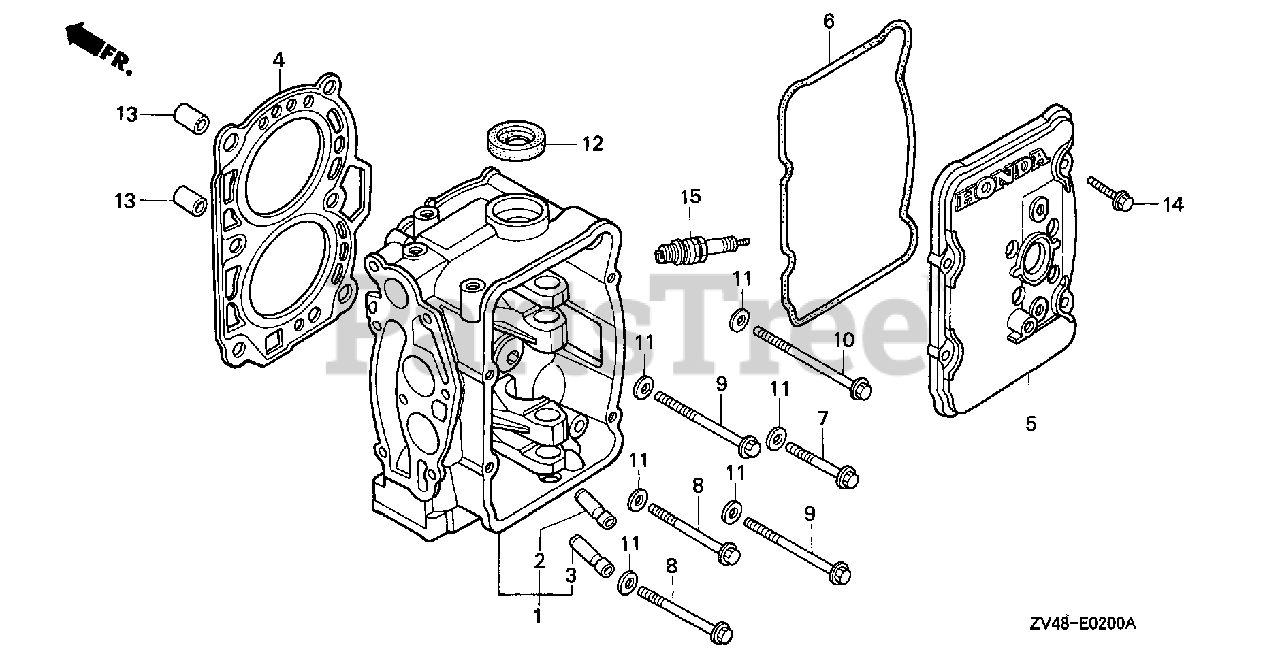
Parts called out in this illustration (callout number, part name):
1	CYLINDER HEAD *NH8* (DARK GRAY)
2	GUIDE, VALVE (OVER SIZE)
3	GUIDE, EX. VALVE (OVER SIZE)
4	GASKET, CYLINDER HEAD
5	COVER, CYLINDER HEAD *NH8* (DARK GRAY)
6	GASKET, HEAD COVER
7	BOLT, FLANGE (8X57)
8	BOLT, FLANGE (8X72)
9	BOLT, FLANGE (8X77)
10	BOLT, FLANGE (8X87)
11	WASHER, HEAD (8MM)
12	OIL SEAL (18X30X7) (NOK)
13	PIN, DOWEL (10X16)
14	BOLT, FLANGE (6X22)
15	SPARK PLUG (DR6HS) (NGK)
15	SPARK PLUG (X20FSR-U) (DENSO)
